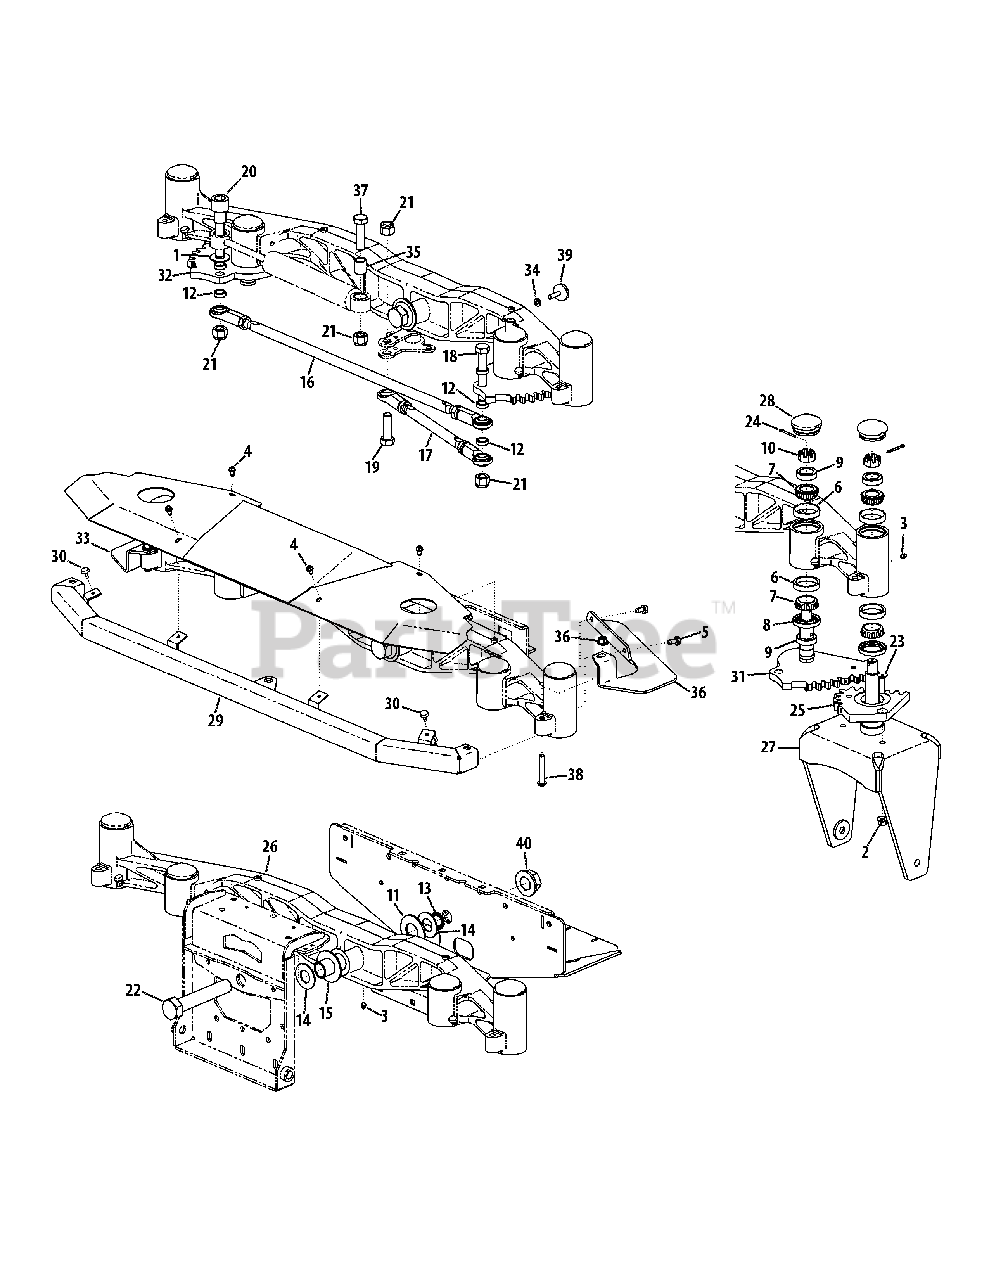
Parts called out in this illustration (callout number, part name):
1	Washer, .655 x 1.5 x .055
2	Flange Counter Lock Nut, 3/8-16
3	Grease Fitting, 1/4-28
4	Hex Flange Screw, 1/4-20 x .500
5	Flange Screw, 5/16-18 x .625
6	Bearing Cup, L44610
7	Cone Bearing, L44643
8	Seal, 14858
9	Seal Ring
10	Slot Nut, 3/4-16
11	Bell Washer, 1.25 x 2.50 x .180
12	Spacer, .635 x .880 x .312
13	Self-Lock External Retainer
14	Washer, 1.00 x 2.00 x .075
15	Spacer, 1.00 x 1.25 x 3.47
16	Tie Rod Assembly, 1/2-20 x 28
17	Tie Rod Assembly, 5/8-18 x 14
18	Hex Screw, 5/8-11 x 4.00
19	Hex Screw, 5/8-11 x 1.75
20	Shoulder Bolt, .872 x 1.030 x 2.88
21	Hex Lock Nut, 5/8-11
22	Hex Screw, 1-14 x 5.5
23	Hex Screw, 3/8-16 x 1.50
24	Cotter Pin, 5/32 x 1.25
25	Yoke Steering Gear
28	Axle Grease Cap
29	Axle Bumper Assembly
30	Rubber Bumper, .62 x .22
31	LH Steering Gear Assembly
32	RH Steering Gear Assembly
35	Spacer, .635 x .875 x 1.031
38	Screw, 3/8-16 x 2.25
39	Adjustable Skid Shoe
40	Flange Top Lock Nut, 1.0-14
